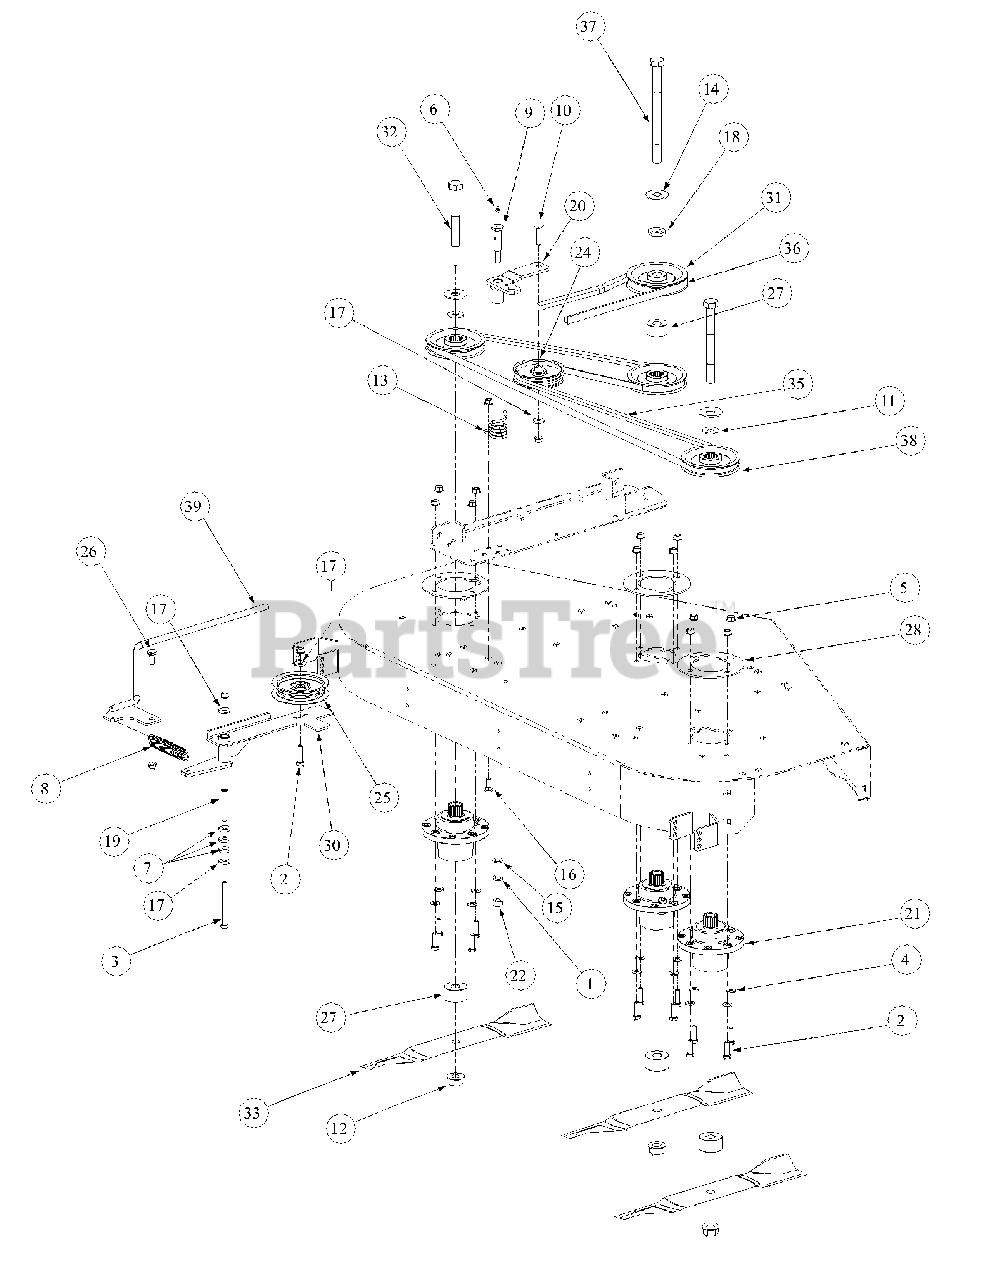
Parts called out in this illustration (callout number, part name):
1	Lock Washer, 7/16
2	Hex Cap Screw, 3/8-16 x 1-1/2
3	Hex Cap Screw, 3/8-16, 3.75
4	Flat Washer, 3/8
5	Hex Nut, Flange Lock, 3/8-16
6	Grease Fitting, 1/4-28 x 3/16
7	Idler Washer
8	Extension Spring, 1.0 OD x 5.125
9	Shoulder Screw, 7/16-14
10	Hex Carriage Screw, 3/8-16, 1.75
11	Spacer, .812 ID x .268 LG
12	Flange Hex Nut, 3/4-16
13	Torsion Spring Idler
14	Flat Washer, .781 ID, 2.00 OD, .105
15	Flat Washer, .469 ID, .875 OD, .105
16	Carriage Bolt, 3/8-16 x 1
17	Flat Washer, .406 ID, 1.0 OD, .105
19	Spacer, .39 ID x .625 OD x 2.75
20	Idler Arm Assembly, Deck Spindle
21	Spindle Assembly, Aluminum Fab Deck
22	Hex Nut, 7/16-14
24	Flat Pulley
25	Idler Pulley, 4.06 OD w/Deep Plan Flanges
26	Shoulder Screw, .50 x .27 LG, 3/8-16
27	Spacer, .760 ID x 2.000 OD x 1.1
28	Plate Support, Cast Aluminum Spindle
30	Idler Arm Assembly, Flat Top Bearing
31	V Pulley, 5.25 OD
32	Hex Cap Screw, 3/4-16, 7.00
33	Hi-Lift Blade, 19.0, 0.756
35	V Belt, A Section x 114.3
36	V Belt, B Section x 87.3
37	Hex Cap Screw, 3/4-16, 9.00
38	V Pulley, 4.65 OD
39	Rod Fab Deck Spring Tension
